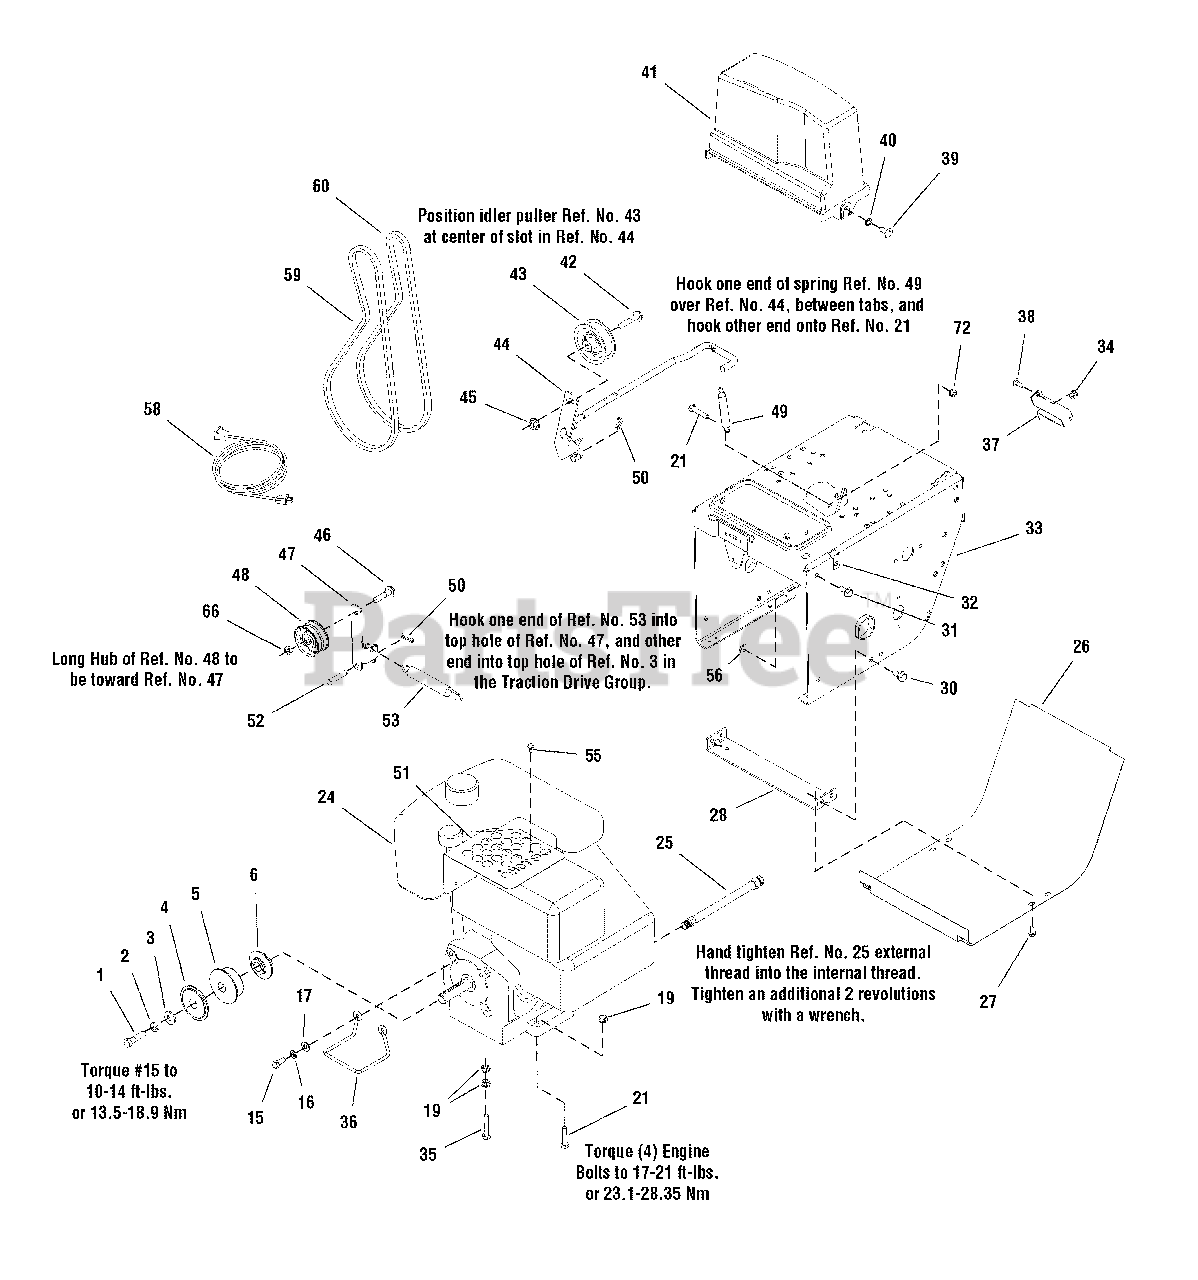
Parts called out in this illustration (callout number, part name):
1	CAPSCREW, Hex Head 3/8-24 x 1-1/2, G8
2	LOCKWASHER, Spring 3/8
3	WASHER, 3/8, .41 ID x 1 OD x .13 THK
4	PULLEY, Engine Outside
5	PULLEY, Engine Middle
6	PULLEY, Engine Inside
15	CAPSCREW, Hex Head 5/16-24 x 3/4, G5
16	LOCKWASHER, Spring 5/16
17	WASHER, 5/16, 0.34 ID x 3/4 OD x .06 THK
19	NUT, Hex Whiz Lock Flange 5/16-18
21	CAPSCREW, Hex Head, 5/16-18 x 1-1/2, G5
25	HOSE, Oil Drain
26	COVER, Bottom Frame
27	SCREW, Hex Washer Head Taptite, 1/4-20 x 1/2
28	SUPPORT, Tie Bar
30	SCREW, Hex Washer Head Taptite, 5/16-18 x 3/4
31	SCREW, Hex Whiz Lock Flange, 5/16-18 x 3/4
32	NUT, Speed, Lug Type, 5/16-18
33	FRAME ASSEMBLY
34	NUT, Hex Keps, 1/4-20 Conical Washer
35	CAPSCREW, Hex Head, 5/16-18 x 1-3/4, G5
36	STOP, Belt
37	SUPPORT, Clutch Cable L.F.
38	CARRIAGE BOLT, 1/4-20 x 3/4, G5
39	SCREW, Truss Head Slotted, 5/16-18 x 3/4
40	LOCKWASHER, External Tooth 5/16
41	COVER, Belt
42	SCREW, Hex Whiz Lock Flange, 3/8-16 x 1-3/4
43	PULLEY, Idler, 2-3/4
44	ROD & ARM ASSEMBLY, Clutch/Brake
45	NUT, Hex Whiz Lock Flange, 3/8-16
46	SCREW, Hex Head, 3/8-16 x 1-1/2 x .141
47	ARM, Idler, 5-3/4
48	PULLEY, Idler
49	SPRING, Extension
50	PIN, Quick
51	GUARD, Muffler
52	PIN, Flat Head Drilled
53	SPRING, Extension L.F.
55	SCREW, Hex Taptite, 10-24 x 1/2
56	NUT, Hex Whiz Lock Flange, 5/16-18
58	CORD, Electric Extension
59	V-BELT, 3L 31.00 (Drive)
60	V-BELT, HA 41.3 (Auger)
66	NUT, Hex Toplock Jam, 3/8-16
72	NUT, Hex Keps Conical Washer, 5/16-18
